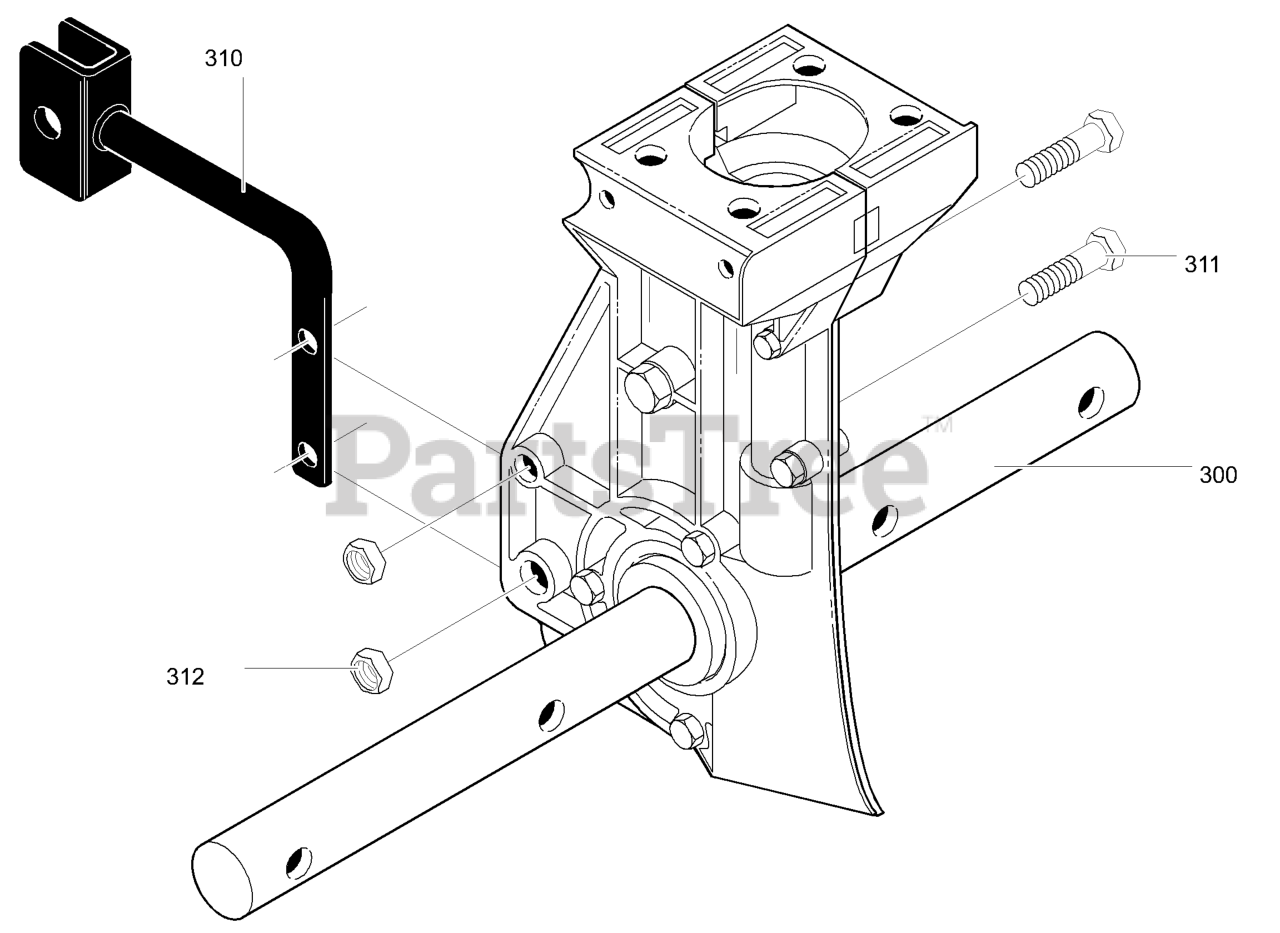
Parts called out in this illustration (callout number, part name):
300	Transmission
310	Bracket, Depth Rod
311	Screw, 1/4-20x1.25
312	Nut, 1/4-20
